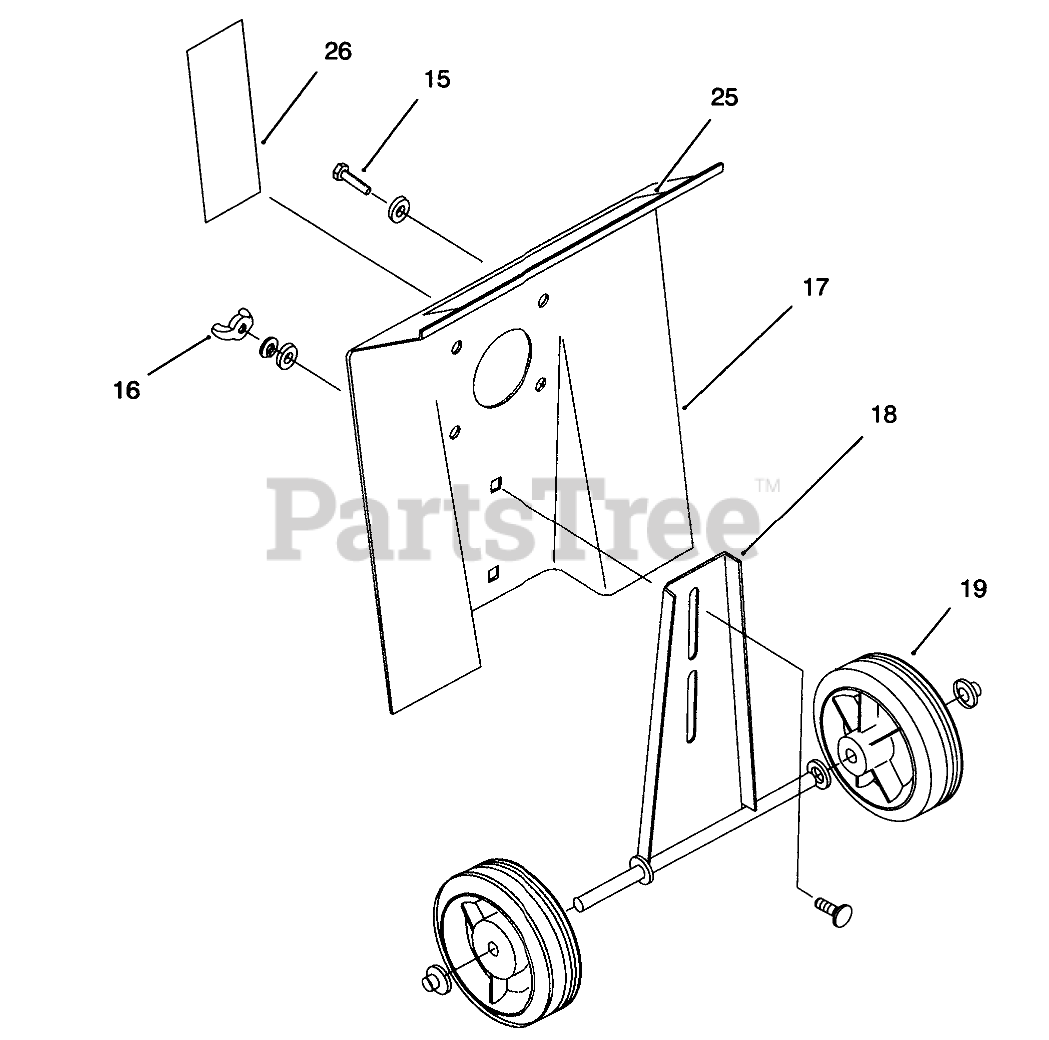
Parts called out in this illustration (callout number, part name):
15	HARDWARE - GUARD MTG
16	HARDWARE-WHEEL BRKT MTG
17	GUARD
18	ASSEMBLY - WHEEL BRACKET
19	ASSEMBLY - WHEEL
25	DECAL - TINE GUARD
26	DECAL - TILLER SAFETY
